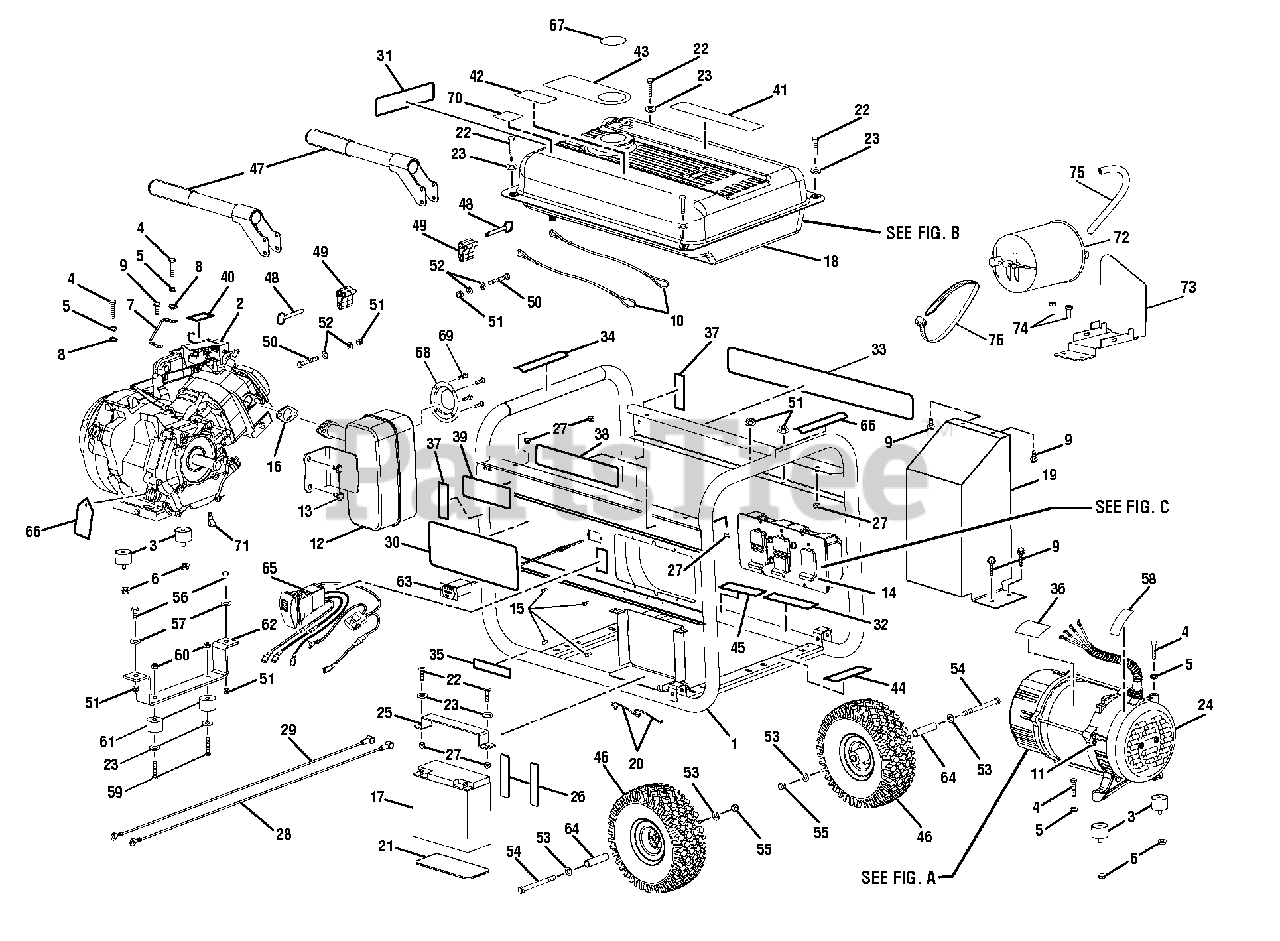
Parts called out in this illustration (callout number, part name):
1	Carrier Assembly
2	Engine (Honda GX390)
3	Isolator
4	Bolt (5/16-18 X 1-1/2 in., Hex Hd.)
5	Lock Washer (5/16 in.)
6	Flange Nut (5/16-18, Hex Hd.)
7	Ground Wire Assembly
8	Star Washer (5/16 in.)
9	Bolt (5/16-18 x 3/4 in., Hex Hd.)
10	Lanyard (3/16 in.)
11	Ground Lug
13	Bolt (5/16-24 x 5/8 in.)
14	Control Panel Assembly
15	Screw (6-20 x 3/8 in.)
16	Muffler Gasket (supplied by Honda)
18	Fuel Tank Assembly
19	Heat Shield
20	Cord Retainer
21	Battery Box Gasket
22	Bolt (1/4-20 X 1 in., Hex Hd.)
23	Washer (1/4 in.)
24	Generator Head w/AVR
25	Battery Hold Down Bracket Assembly
26	Gasket (Battery Hold Down Bracket)
27	Lock Nut (1/4-20)
28	Battery Cable (Red)
29	Battery Cable (Black)
30	Logo Label
31	Starting Instructions Label
32	Hot Surface Label
33	DangerLabel
34	Fire Danger LabeL
35	Engine Lubricant Label
36	Data Plate Label
37	Locking Pin Label
38	Honda Label
39	Electric Start Label
40	Choke Label
41	Quick Start Label
42	CPSC Label
43	Hangtag (Engine Warning)
44	Ground Warning Label
45	Combustion Warning Label
46	Wheel Assembly
47	Handle Assembly
48	Release Pin (5/16 x 2 in.)
49	Handle Bracket Spacer
50	Bolt (5/16-18 x 2-1/4 in., Hex Hd.)
51	Lock Nut (5/16 in.)
52	Washer (5/16 in.)
53	Washer (3/16 in.)
54	Bolt (3/8-16 x 4-1/4 in., Hex Hd.)
55	Nut (3/8-16)
56	Bolt (5/16-18 X 1 in., Hex Hd.)
57	Flat Washer (5/16 in.)
58	Ground Label
59	Bolt (1/4-20 X 1-1/2 in., Hex Hd.)
60	Lock Nut (1/4-20)
61	Rubber Foot
62	Front Foot
63	Hour Meter (120 Volt)
64	Wheel Spacer
65	Engine Switch
66	Fire Distance Label
67	Fuel Stabilizer
68	Spark Arrestor
69	Screw (8-32 x 3/8 in.)
70	E85 Label
72	Canister
74	Bolt (5/16-18 x 3/4 in.)
75	Purge Hose
76	Cable Tie
